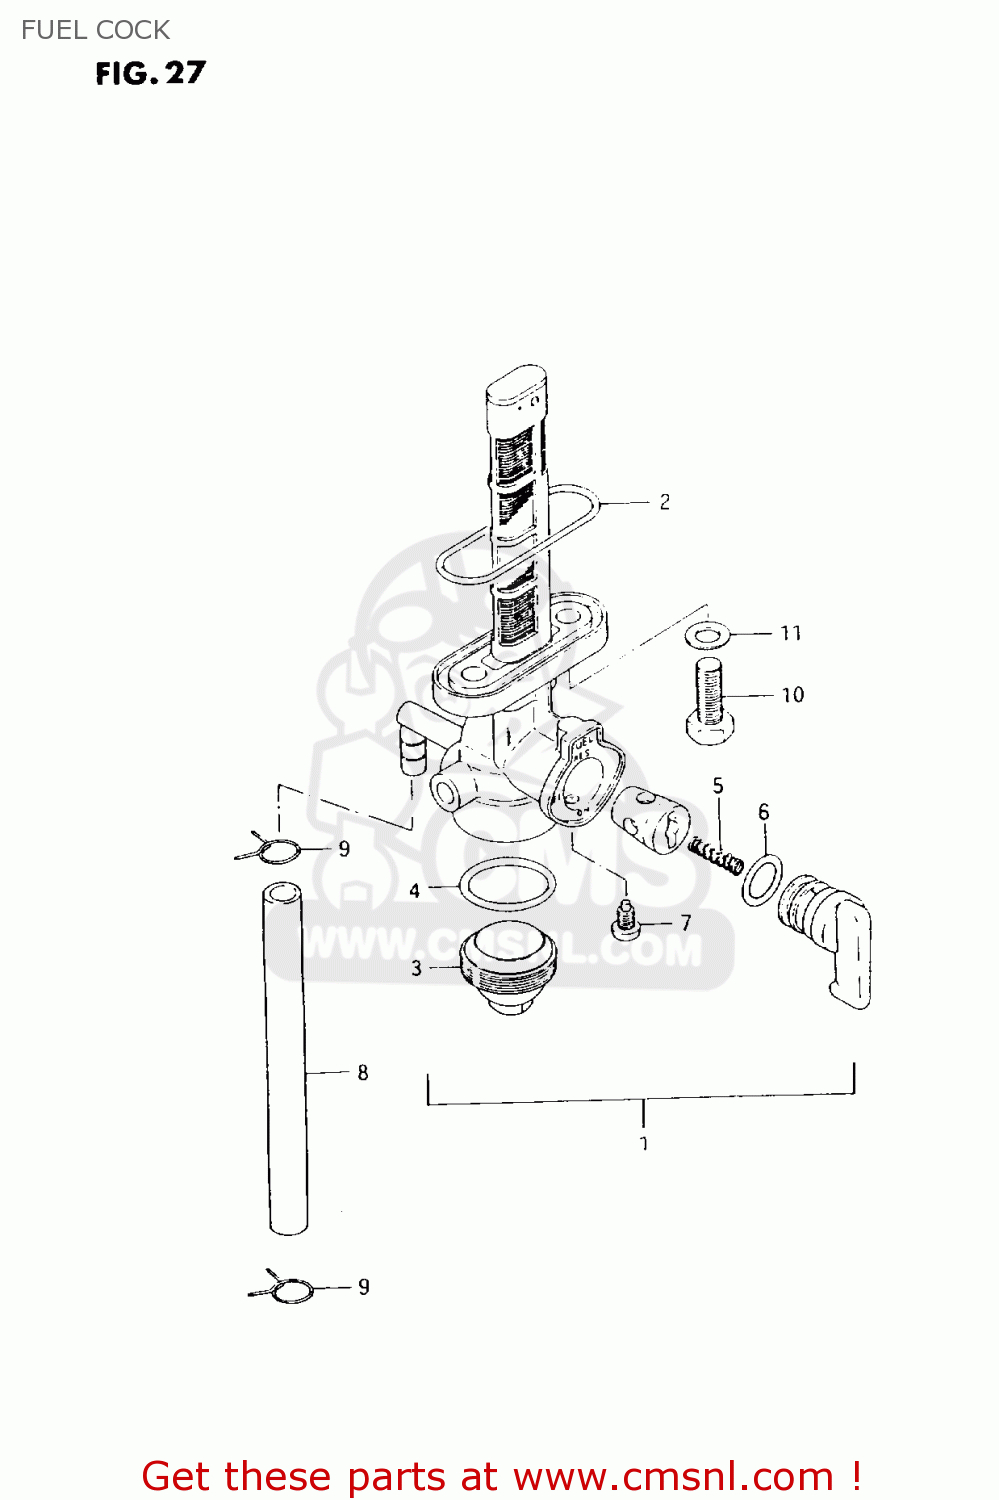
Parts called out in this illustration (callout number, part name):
1	COCK ASSEMBLY,FUEL
2	O RING,FUEL COCK
3	CUP,STRAINER
4	GASKET,FILTER (NAS)
5	SPRING
6	O RING,LEVER
7	SCREW
8	HOSE(5X8.2X600)
9	CLIP
10	BOLT(6X20)
11	GASKET(6.4X11.5X0.8) (NAS)
